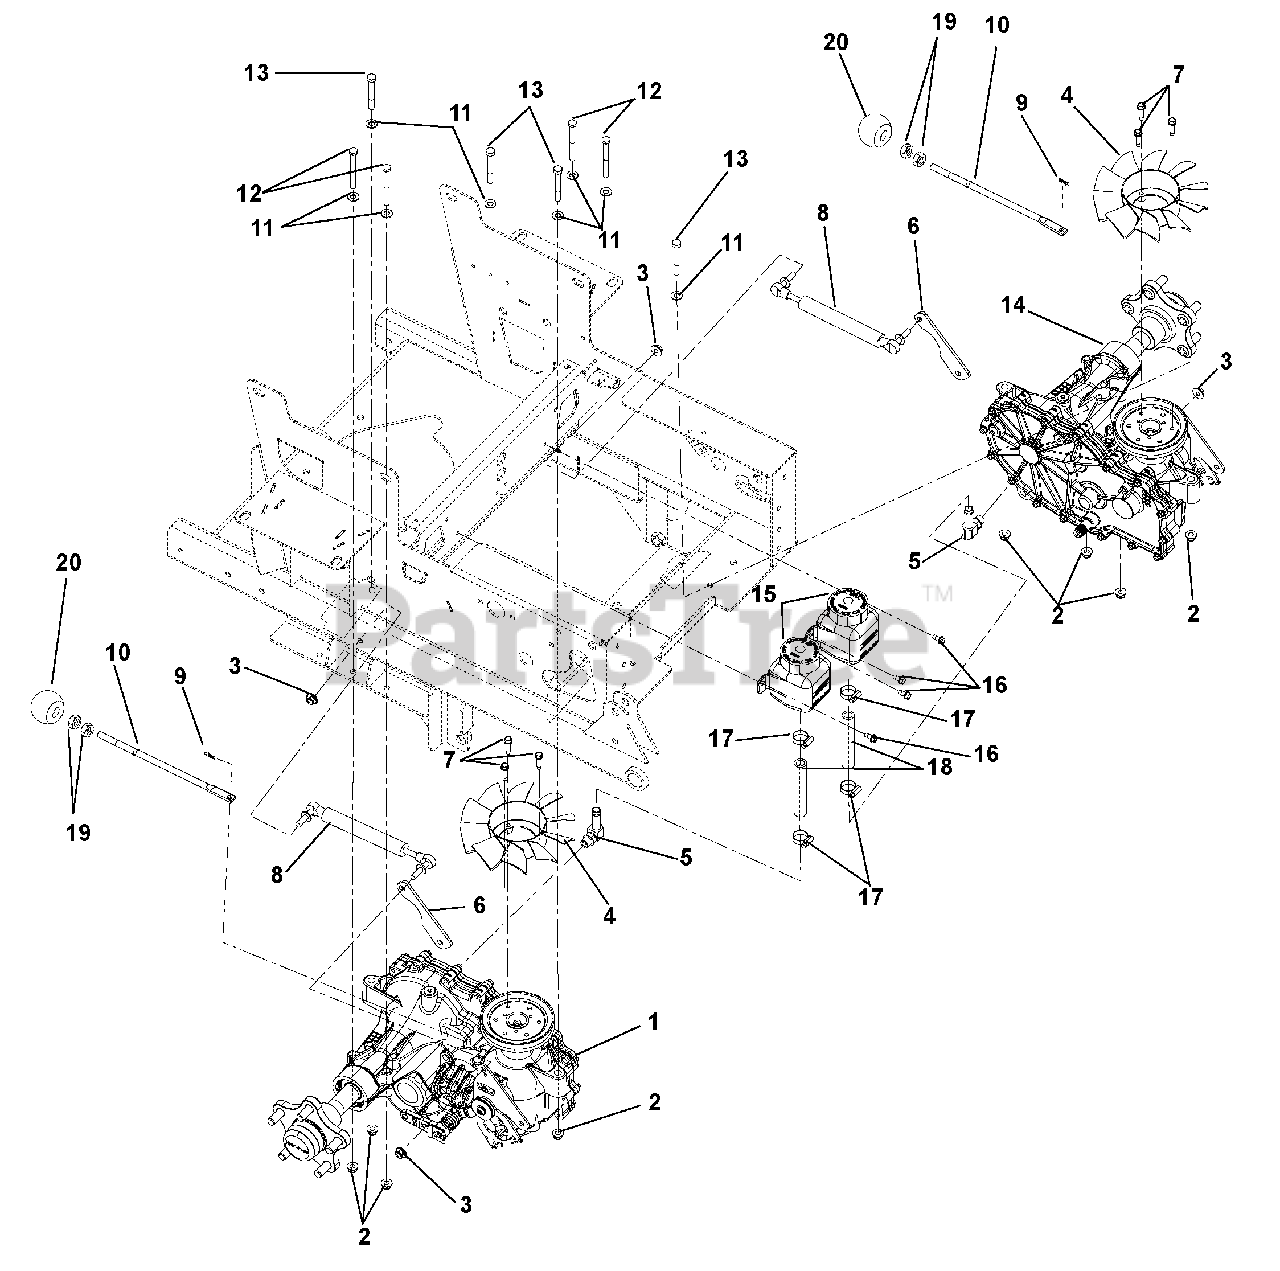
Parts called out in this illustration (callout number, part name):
1	TRANSAXLE, RH 3400
2	NUT-LK-NYL-FLG .31-18 YWZC
3	NUT, M8-1.25 WHIZ LOCK YWZC
4	FAN, 2800 SERIES COOLING
5	FITTING, HYD (90 DEG)
6	PLATE, CONTROL REINFORCEMENT
7	SCR-TAP .25-20X1.00 HWH TR YZ
9	PIN-HAIR INT .06X.18X.77
10	LEVER, PT100 DUMP VALVE
11	WSHR-FL-STL.344X.688X.065YWZC
12	BLT-HEX .31-18X3.00 GR5 YWZC
13	BLT-HEX .31-18X2.50 GR5 YWZC
14	TRANSAXLE, LH 3400
15	TANK, EXPANSION ZT2800
16	SCR-TAP .25-20X.50 HWH TR YWZ
17	CLAMP,.88 DIA. HOSE
18	HOSE, 100I HYDRO OVERFLOW
19	NUT- JAM .312-18 YWZC
20	KNOB-BALL-BLACK .312-18 X 1.00
